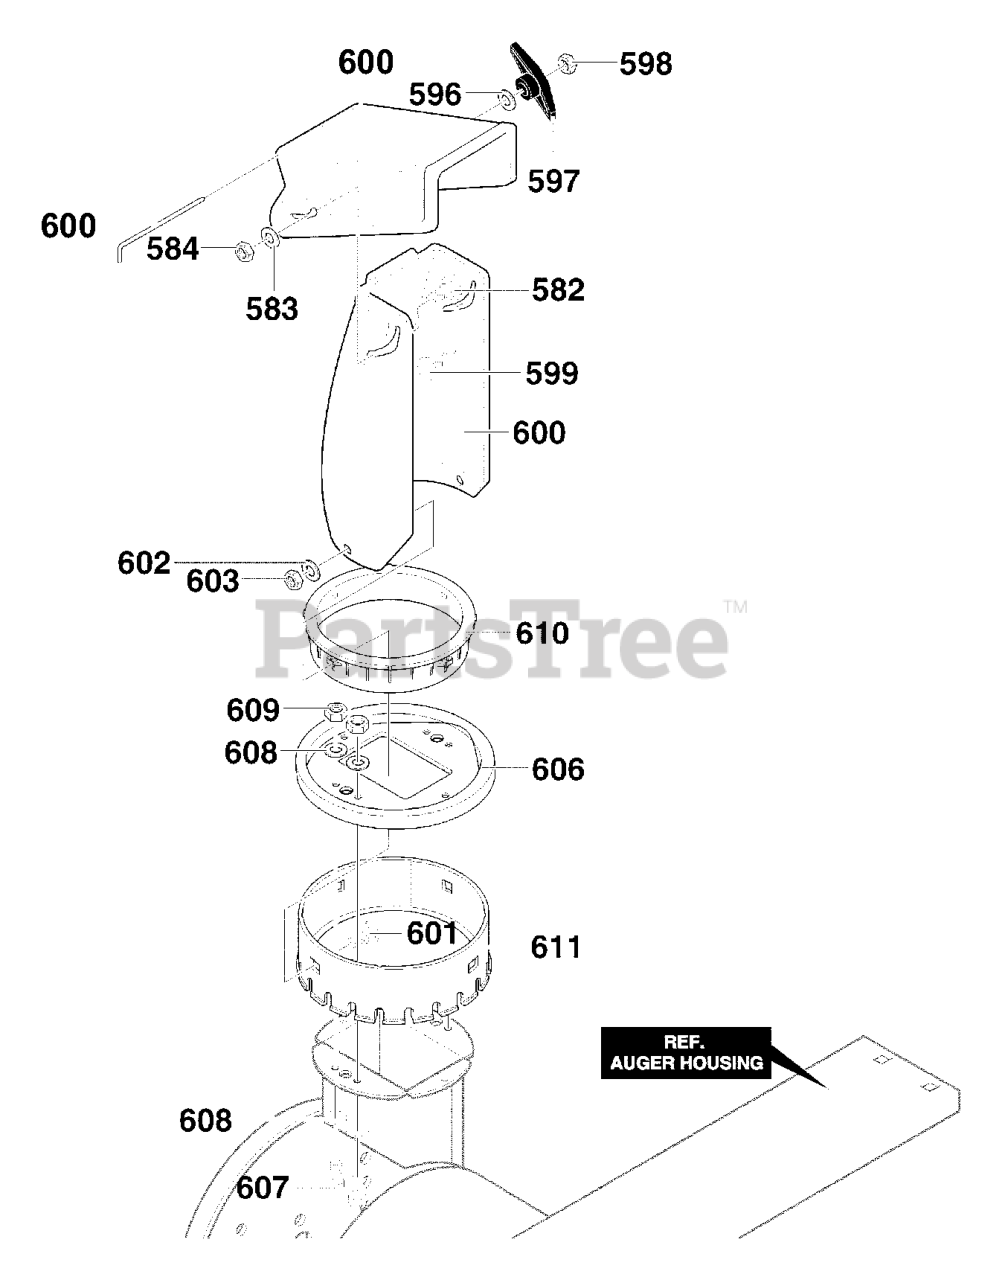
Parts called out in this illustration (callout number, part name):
582	SCREW, 5/16-18 x 0.75
583	WASHER, FLAT
584	NUT, 5/16-18
596	WASHER, FLAT
597	KNOB, T
598	NUT, 5/16-18 REGHEX
599	BOLT 5/16-18X1.25 CARR.
600	CHUTE, ASSEMBLY
601	BOLT, 5/16-18X1.00
602	FLATWASHER
603	NUT, 5/16-18
606	COLLAR, CHUTE
607	SCREW, 1/4-20X .75
608	FLATWASHER
609	NUT, 1/4-20 HEX NYLOCK
610	RETAINER, RING INNER
611	RETAINER, RING OUTER
